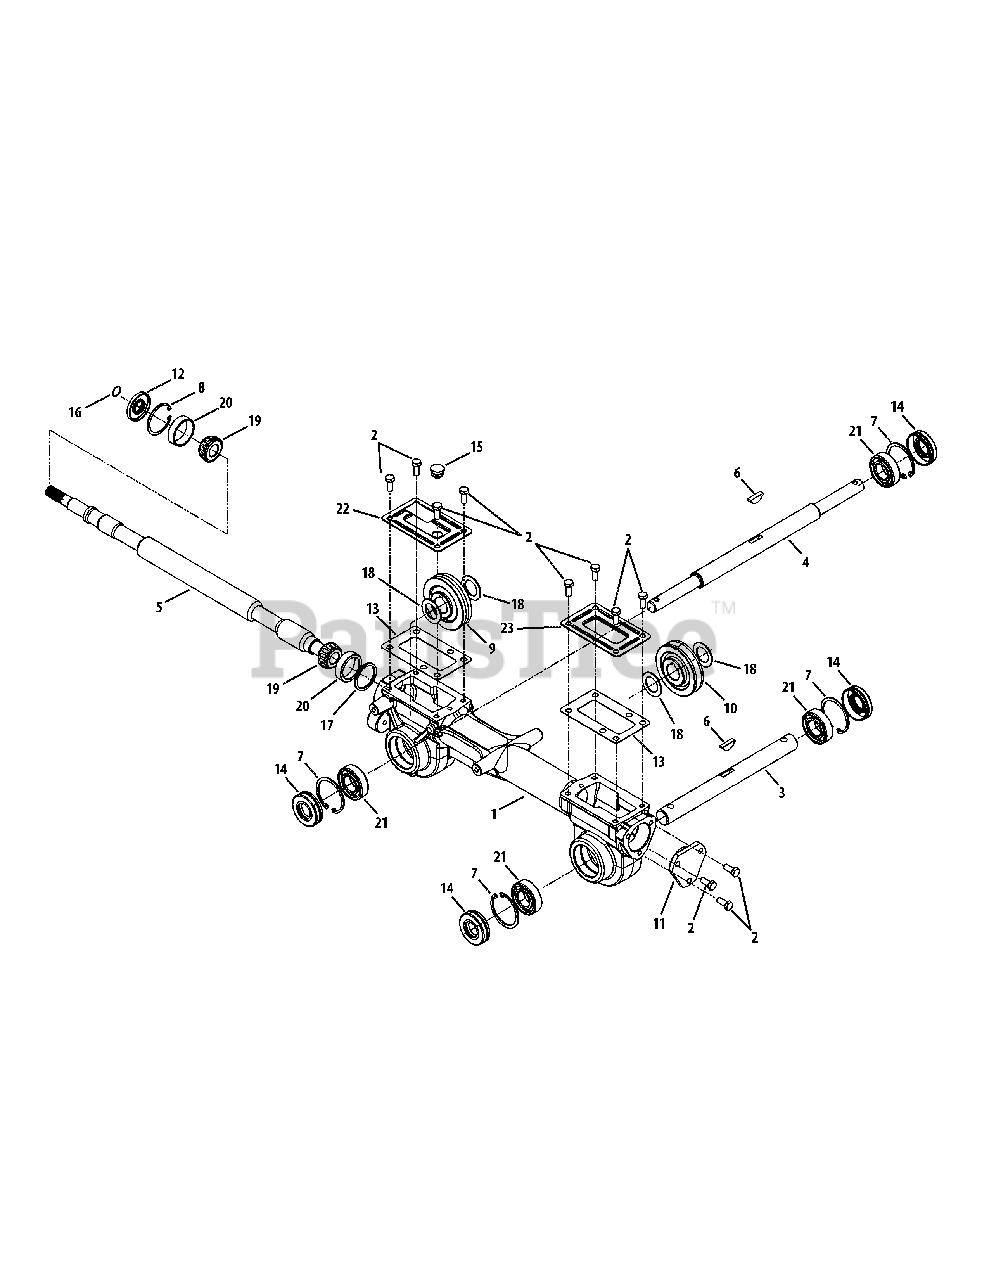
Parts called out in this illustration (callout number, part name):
1	Housing, Transmission
2	Hex Screw, 5/16-18, .75, Gr5
3	Shaft, Tiller
4	Shaft, Wheel
5	Shaft, Worm
6	Key, Hi Pro .25 x 1.062
7	Retaining Ring
8	Retaining Ring, Int
9	Worm Gear, 61t, RH
10	Worm Gear, 30t, LH
11	Bearing Cover
12	Seal, Oil, .750 Shaft x 1.783 Bore
13	Gasket, Gear Housing
14	Seal, Oil, 1.00 Shaft x 2.00 Bore
15	Rubber Plug, Oil
16	Wire Ring
17	Washer, Flat, 1.50 x 1.75 x .062
17	Washer, Flat, 1.50 x 1.75 x .005
17	Washer, Flat, 1.50 x 1.75 x .03
17	Washer, Flat, 1.50 x 1.75 x .010
18	Washer, Flat, 1.010 x 1.56 x .060
19	Cone Bearing
20	Bearing Cup
21	Ball Bearing
22	Cover, Transmission
23	Cover, Transmission
